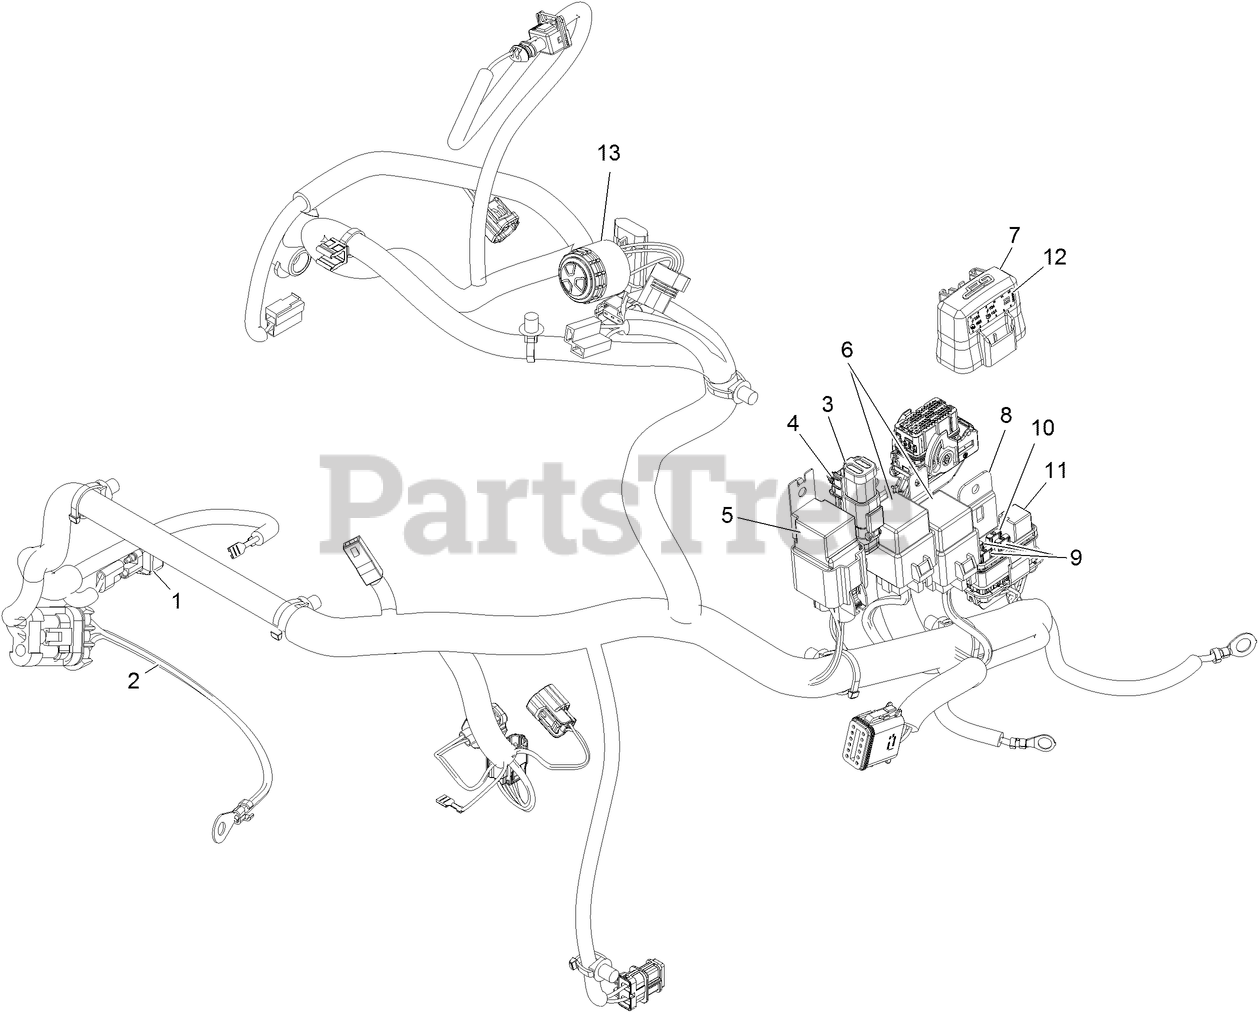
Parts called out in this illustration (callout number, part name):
2	HARNESS-WIRE, FUSIBLE LINK
3	CONNECTOR (6M)
4	CLIP-CONNECTOR
5	RELAY-70A
6	RELAY-MINI
7	COVER-BLOCK, FUSE
8	CLIP-MOUNTING
9	FUSE-MINI BLADE, 15 AMP
10	FUSE-MINI BLADE, 10 AMP
11	RELAY-MICRO
12	DECAL-FUSE
13	ALARM-DUAL TONE
